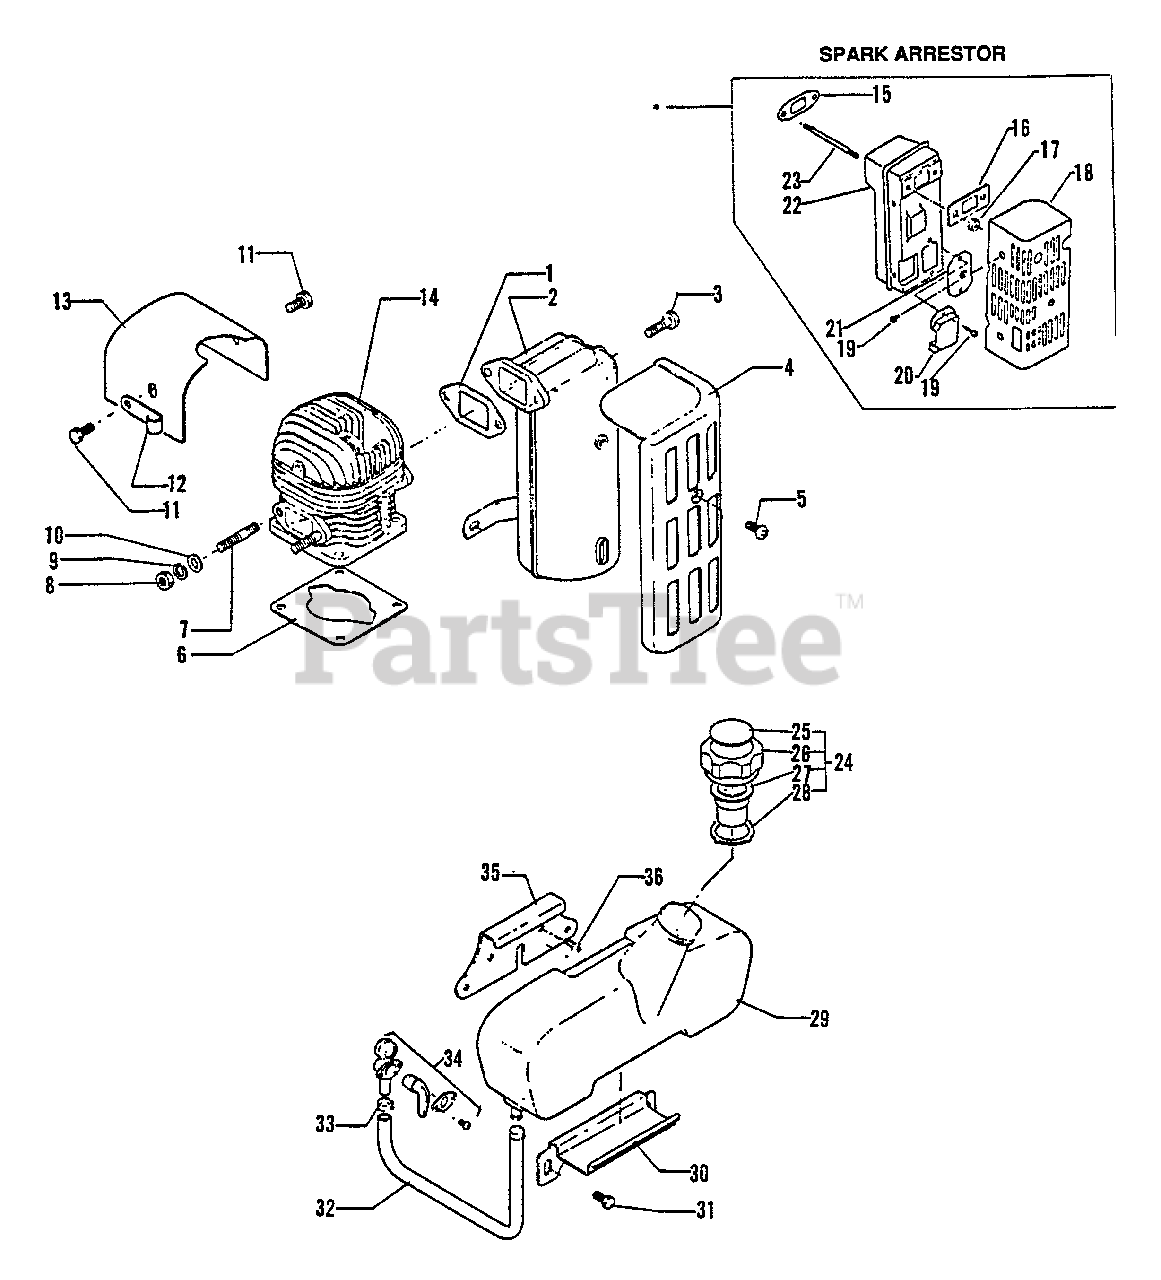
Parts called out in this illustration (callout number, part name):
1	GASKET, EXHAUST
2	MUFFLER
3	BOLT - 6X20
4	COVER, MUFFLER
5	SCREW - 5X14
6	GASKET, CYLINDER
7	STUD
8	LOCKNUT - 6
9	LOCKWASHER - 6
10	WASHER - 6
11	BOLT - 6X10
13	SHIELD, CYLINDER
14	CYLINDER
15	GASKET, EXHAUST
18	COVER, EXHAUST
19	SCREW - 5X10
20	RETAINER, SCREEN
21	SCREEN, SPARK ARRESTOR
23	STUD
24	CAP ASSY
25	LABEL - FUEL MIX
26	CAP, FUEL
27	VENT, CAP
28	GASKET, CAP
29	TANK, FUEL
30	BRACKET, FUEL TANK
31	BOLT - 6X12
32	PIPE - FUEL
33	CLAMP
34	FUEL VALVE ASSY
35	BRACKET, FUEL TANK
36	SCREW - 5X14
